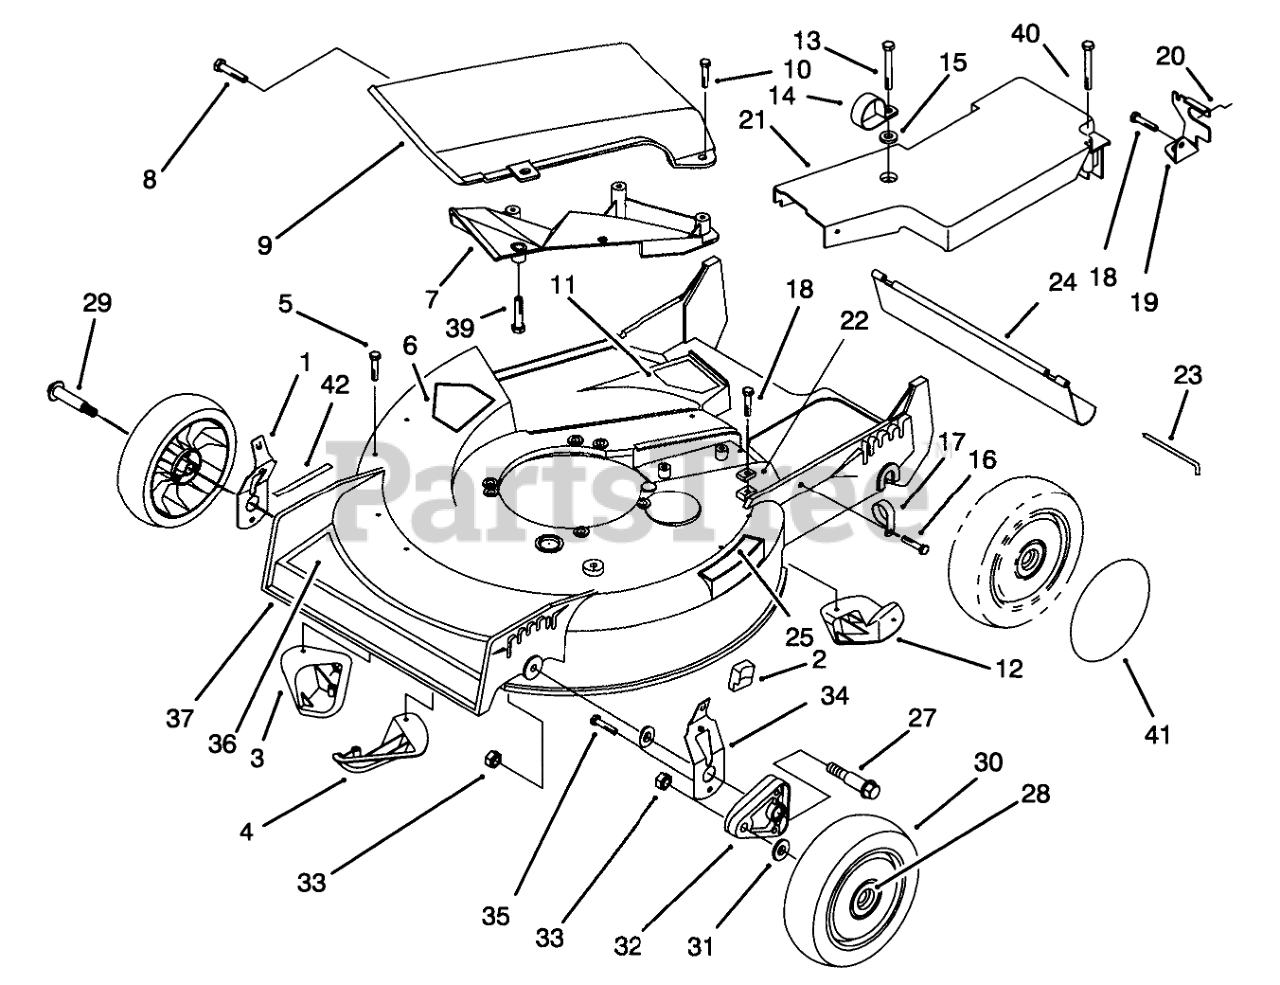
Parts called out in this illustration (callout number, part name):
1	RH SPRING ARM ASM
2	KNOB-ARM
3	KICKER-FRONT
4	KICKER-RH
5	SCREW-PPH
6	DECAL-DANGER
7	Deflector-Recycler
8	SCREW AND WASHER ASM
9	Recycler Cover Assembly (Incl. Ref. #7 & 39)
10	SCREW-HWH
11	DECAL - DANGER
12	KICKER-REAR
13	SCREW-SPECIAL
14	CLAMP-CABLE
15	WASHER
16	SCREW-HWH
17	CLAMP-CABLE
18	SCREW-HWHTF
19	Bracket-Adj. Trac
20	RETAINER-CABLE
21	BELT COVER
22	CLAMP-CABLE
23	ROD-SHIELD
24	SHIELD-TRAILING
25	STEP PAD DECAL
27	BOLT-SHOULDER
28	BUSHING
29	BOLT-WHEEL
30	Wheel & Tire Assembly (Incl Ref. #28)
31	WASHER
32	ARM-PIVOT, FRONT
33	NUT-LOCK
34	LH SPRING ARM ASM
35	SCREW-HWH
36	DECAL - DECK
37	Housing Assembly (Incl. Ref. #3-6, 8,11,12,& 42, Pg.1)(Incl. Ref. #5-6, Pg. 3)
39	Screw-Plastite
40	SCREW-HHFTF
41	WHEEL COVER
42	DECAL - HOC
